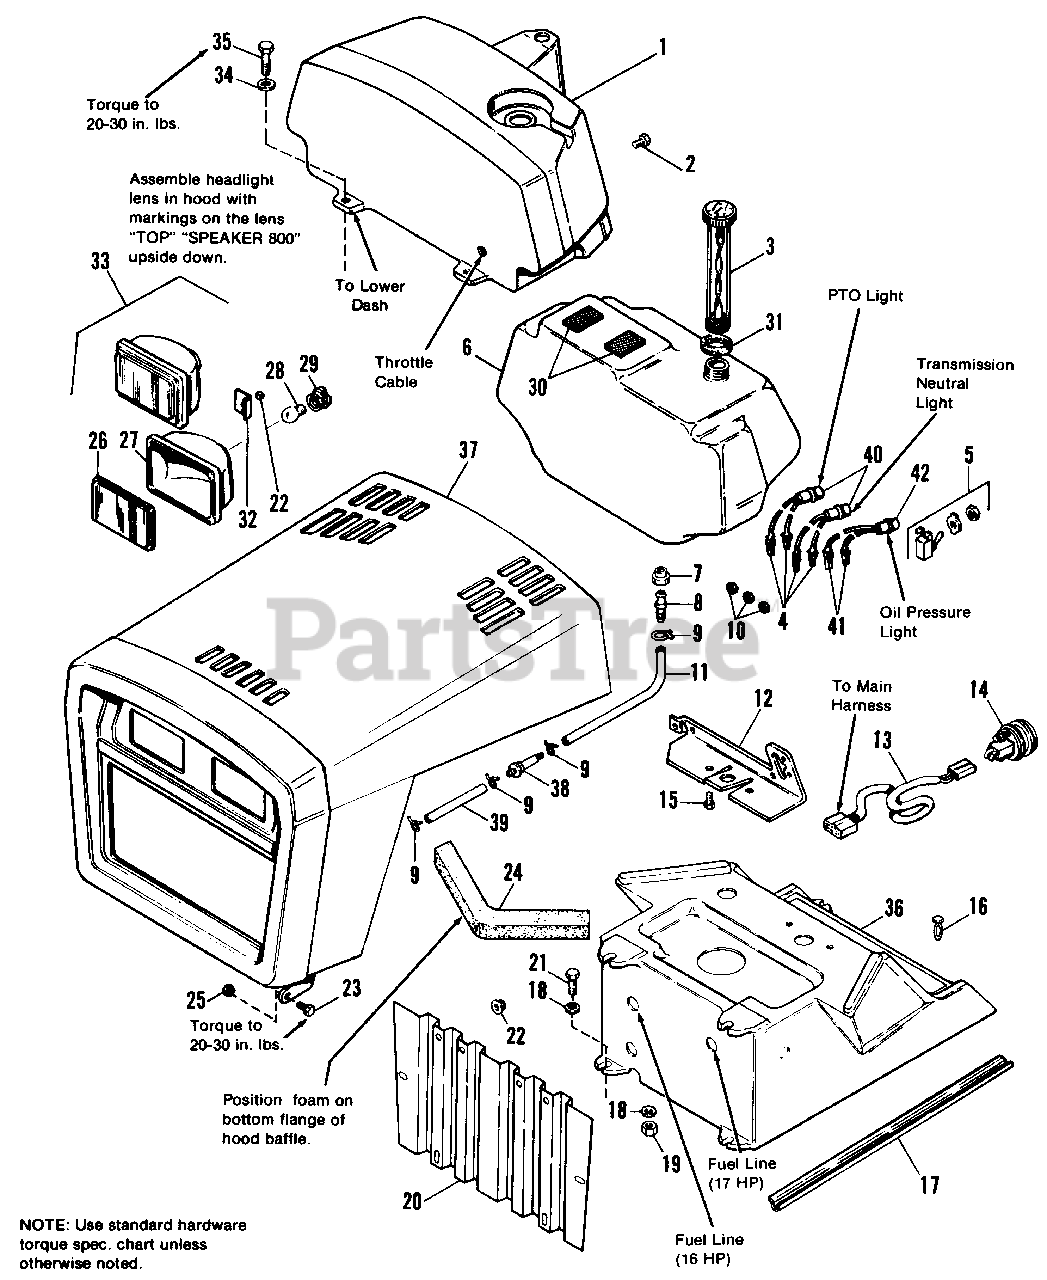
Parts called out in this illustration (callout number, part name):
1	DASHBOARD, Top
2	SCREW, Type "AB" 1/4-14 x 5/8
3	CAP, Fuel Tank
4	LIGHT, Indicator (Incl. Ref. No. 40)
5	SWITCH, Toggle (Lights)
6	TANK ASSY., Fuel (Incl. Ref. Nos. 7, 8, 9 & 11)
9	CLAMP, Hose (Qty. 4 on 1691824)
10	NUT, Push On
11	HOSE, Fuel (Cut to 12"HOSE, Fuel, Cut to 12th)
11	HOSE, Fuel (Cut to 8-5/8"HOSE, Fuel, Cut to 12th)
12	BRACE, Dashboard
13	WIRE ASSY., Upper
15	SCREW, Taptite, 1/4-2 x 3/4
16	CLIP, Canoe
17	EDGING, Lower Dash
18	LOCKWASHER, Dished, 1/4
19	LOCKNUT, 1/4-20
20	SCREEN, Grille
21	SCREW, Taptite, 1/4-20 x 1
22	NUT, Pal, Hex, #10-24
23	CAPSCREW, 3/8-16 x 7/8
24	SEAL, Hood Baffle
25	LOCKNUT, 3/8-16
26	LENS, Clear
29	SOCKET, Bulb
31	WASHER, Foam
32	CLIP, Headlight Mtg.
33	HEADLIGHT ASSY. (Incl. Ref. Nos. 26,27,28 & 29)
34	WASHER, 1/4
35	SCREW, Hex, 1/4-20 x 1-1/4
36	DASHBOARD, Bottom
37	HOOD & GRILLE ASSY.
38	FILTER, Fuel
39	HOSE, Fuel
40	LENS CAP, Green
41	LIGHT, Indicator (Incl. Ref. No. 42, Qty. 1)
42	LENS CAP, Red
